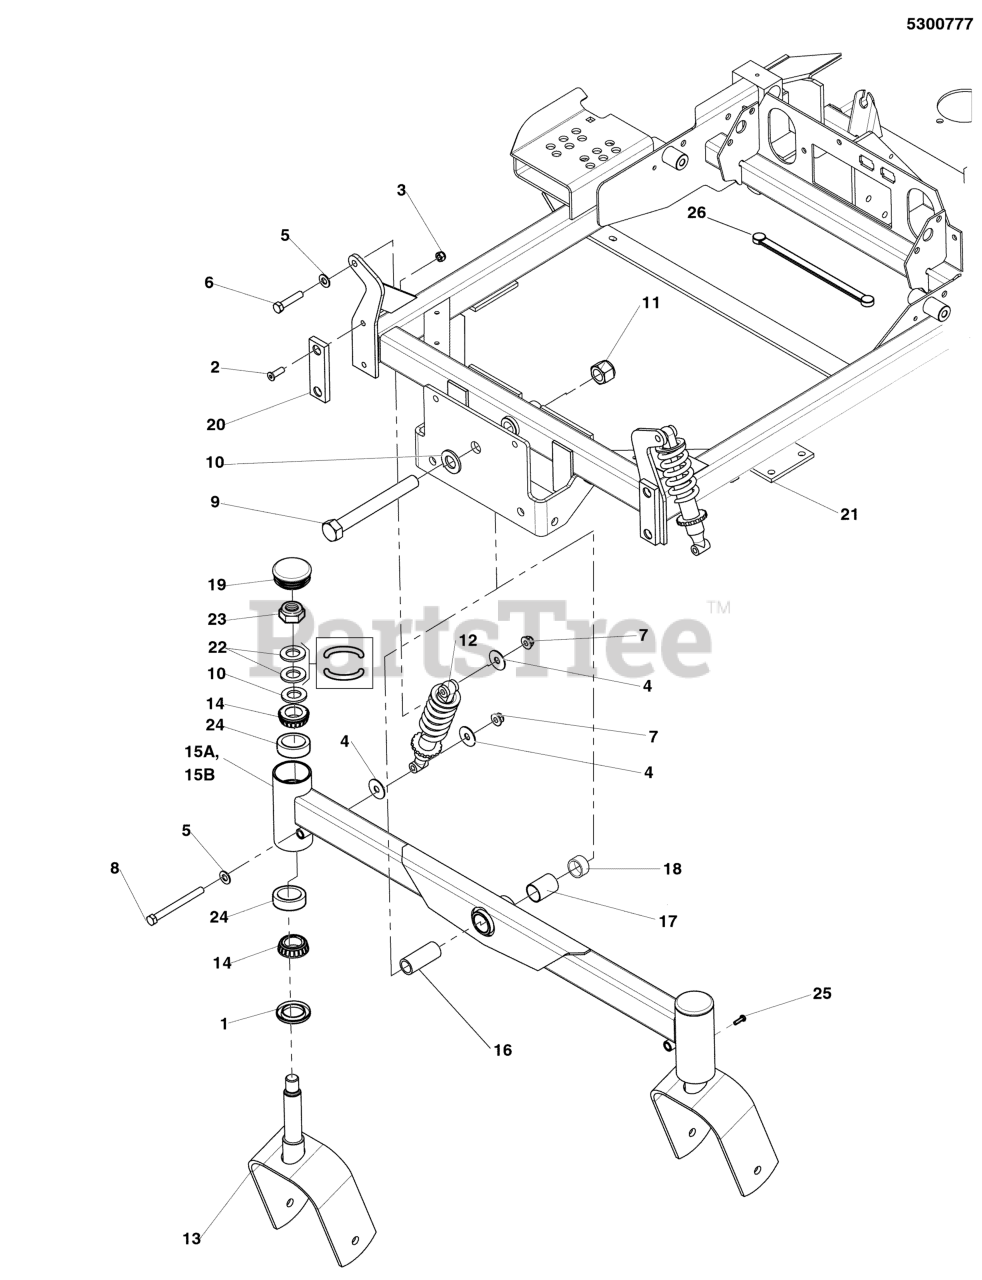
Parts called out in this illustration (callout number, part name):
1	SEAL, GREASE
2	SCREW, 5/16-18 X 1 PHILLIPS HD, BZ
3	NUT, 5/16-18 HEX NYLON LOCK
4	WASHER, 3/8" FENDER
5	WASHER, 3/8 SAE
6	BOLT, 3/8-16 X 1-3/4" GD5 CZ
7	NUT, 3/8-16 HEX NYLOCK FLANGE
8	BOLT, 3/8-16 X 4" GD5 CZ
9	BOLT, 3/4-16 X 6-1/2" YZ GD5
10	WASHER, 3/4 SAE
11	NUT, 3/4-16 HEX NYLON LOCK
12	SHOCK, SPRING ASSEMBLY
13	WELD, CASTER YOKE - RED
14	BEARING, TAPERED ROLLER, 1"
16	SPACER, .75 X 1.00 X 2.38
17	PIVOT BEARING, 1.00" X 1.125" OD X 1.50"
18	PIVOT BEARING, 1.00" X 1.125" OD X .50"
19	CAP, GREASE, LOW PROFILE
20	PAD, FRICTION, .375 X 1.25 X 4.00
21	WELD, IS500 MAIN FRAME - RED
22	WASHER, BELLEVILLE
23	NUT, 3/4-16, HEX JAM NYLON LOCK
24	BEARING CUP
25	BOLT, 1/4-28 X 1/2" GD5 YZ
26	STRAP-BLACK RUBB
